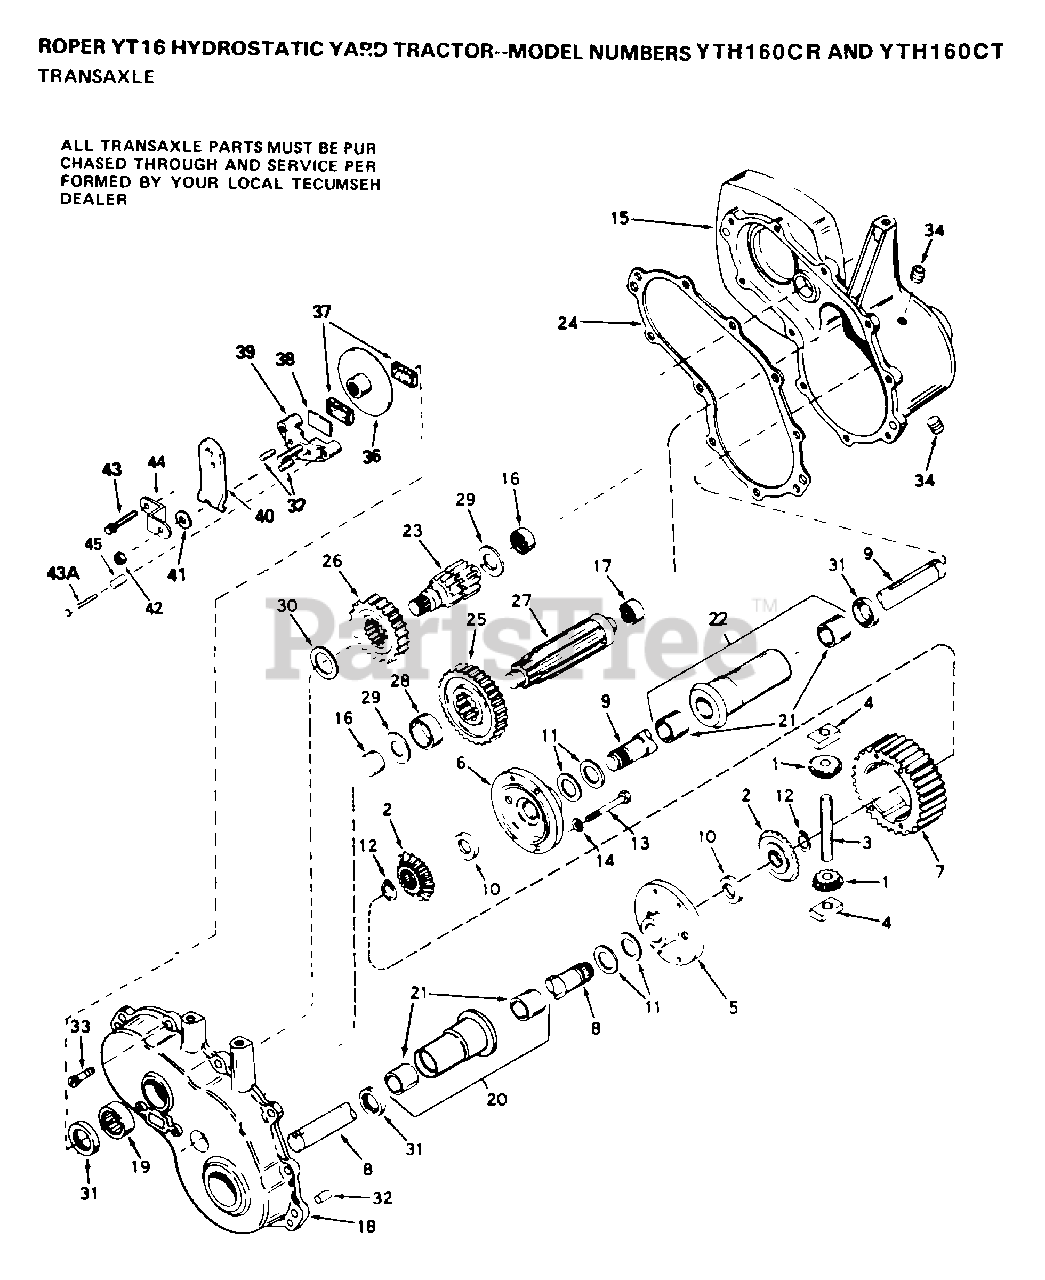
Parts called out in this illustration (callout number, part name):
1	PINION, 10T
4	BLOCK DRIVE
5	CARRIER, DIFFERENTIAL
6	CARRIER, DIFFERENTIAL
11	WASHER THRUST
13	SCREW, 1/4-20 X 2-1/4
14	WASHER LOCK 1/4
16	BEARING, NEEDLE
17	BEARING, NEEDLE
19	BEARING, NEEDLE
20	HOUSING & BUSHING ASSY
22	HOUSING & BUSHING ASSY
23	SHAFT, BRAKE
25	GEAR, OUTPUT
26	GEAR, IDLER
27	SHAFT, OUTPUT
30	WASHER, THRUST
36	DISK, BRAKE
38	PLATE BRAKE PAD
39	HOLDER BRAKE PAD
40	LEVER, BRAKE
41	WASHER, FLAT
42	LOCKNUT 5/16-24
43	SCREW, 1/4-20 X 1-1/4
43A	SCREW FLNG HEX 1/4-20 X 2-1/4
44	BRKT BRAKE LEVER
